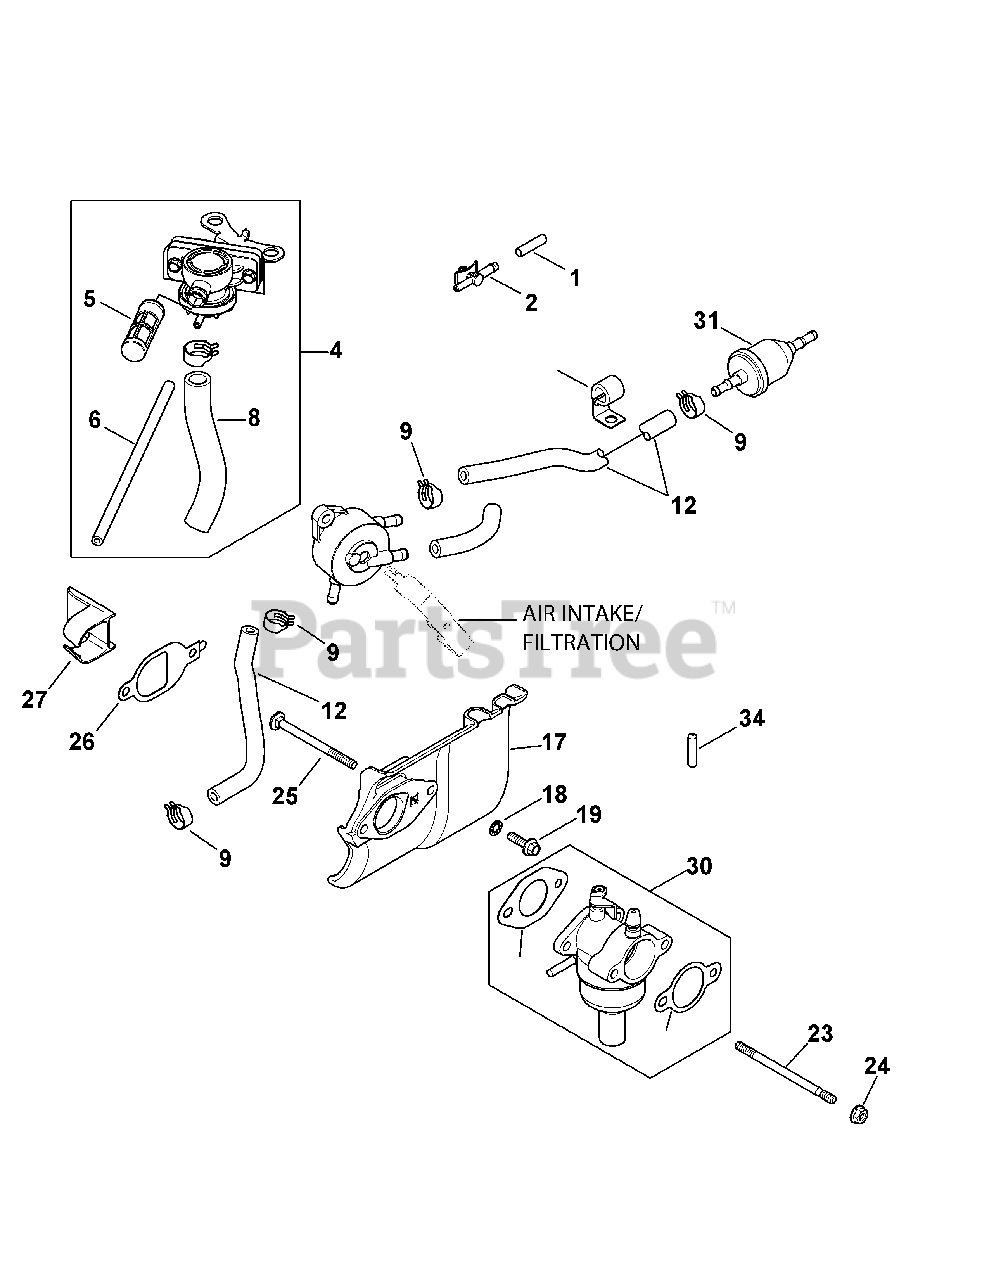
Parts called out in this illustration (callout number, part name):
2	SAI Connector
4	Fuse Block
5	Fuse Block
6	Fuse Block
8	Fuse Block
9	Hose Clamp, 1/2
12	Fuel Line
17	Heat Deflector Kit
18	Int. Tooth Lock Washer, 1/4
19	Flange Screw, M6 X 1.0 X 20
23	Stud, M6 X 1.0 X 100
24	Flange Nut, M6 X 1.0
25	Carburetor Stud
26	Heat Deflector Gasket
30	Carburetor Kit
30	Gasket, carburetor
30	Gasket, air cleaner
34	not used in this application
